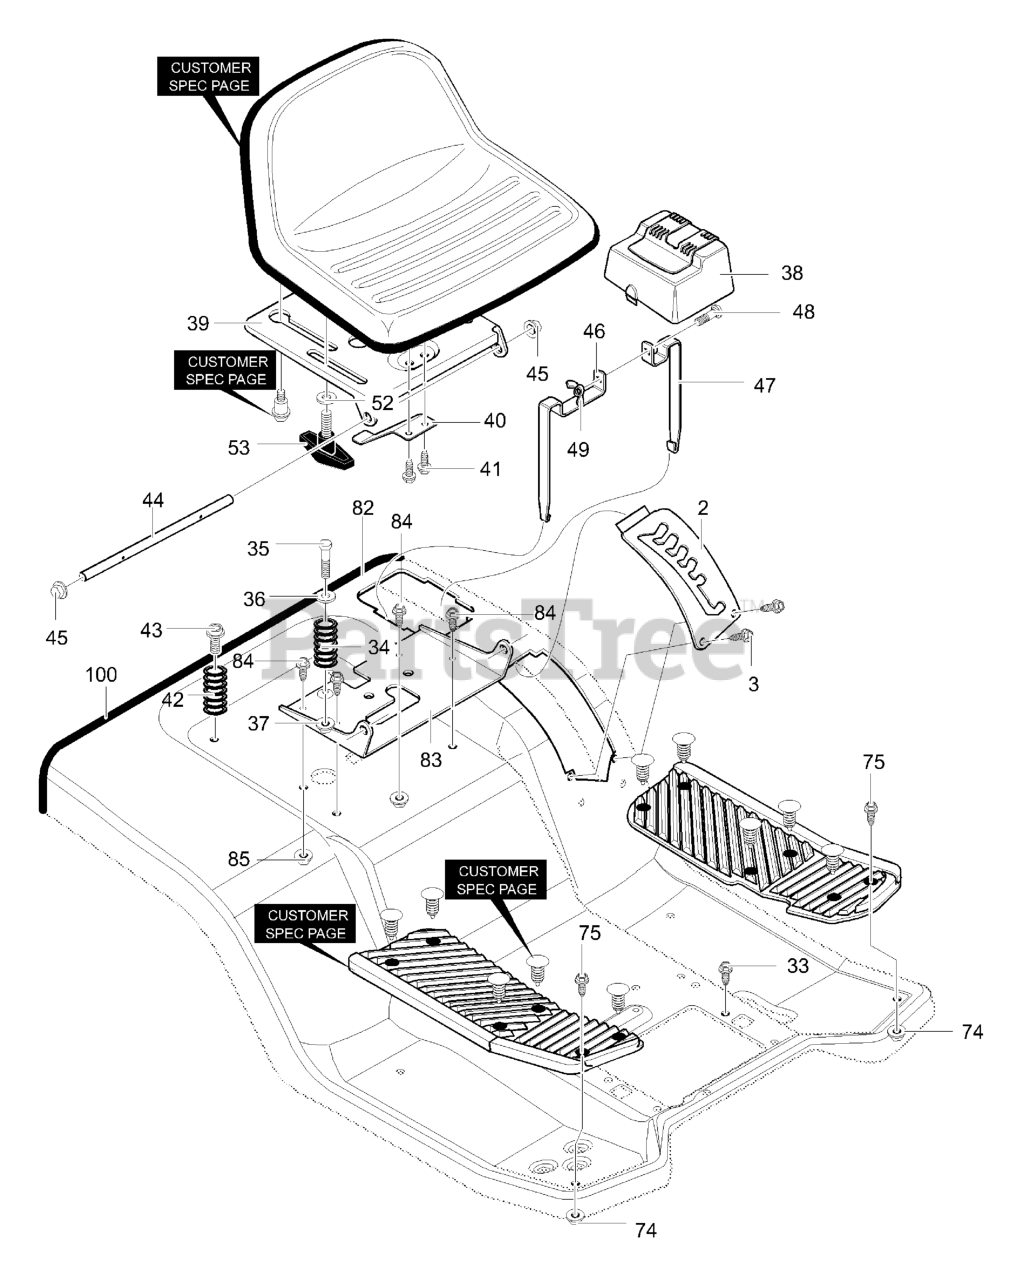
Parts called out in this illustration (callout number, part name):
2	Plate, Lift Detent
3	Screw, #12x.50
33	Screw, 5/16-18 x 0.75
34	Spring, Compression
35	Shoulder Bolt 1/4-20
36	Zinc Washer Cup
37	Nut, 1/4-20 Centerlock
38	Cover, Battery
39	Support, Seat
40	Spring - Leaf
41	Screw, 1/4-20x.50
42	Spring, Compression
43	Screw, 5/16-18 x 0.75
44	Hinge Seat Pivot
45	Nut, Push Cap
46	Battery Bracket, LH
47	Battery Bracket, RH
48	Bolt, Carriage 1/4-20x.63
49	Nut, Wing 1/4-20
52	Washer, Flat
53	Bolt, Wing 5/16-18x.50
74	Nut, 5/16-18
75	Bolt, Carriage 5/16-18x.75
82	Seat Deck Pedal
83	Bracket, Pivot Seat
84	Screw, 5/16-18 x 0.75
85	Nut, 5/16-18
100	Trim 41.00 Inches
